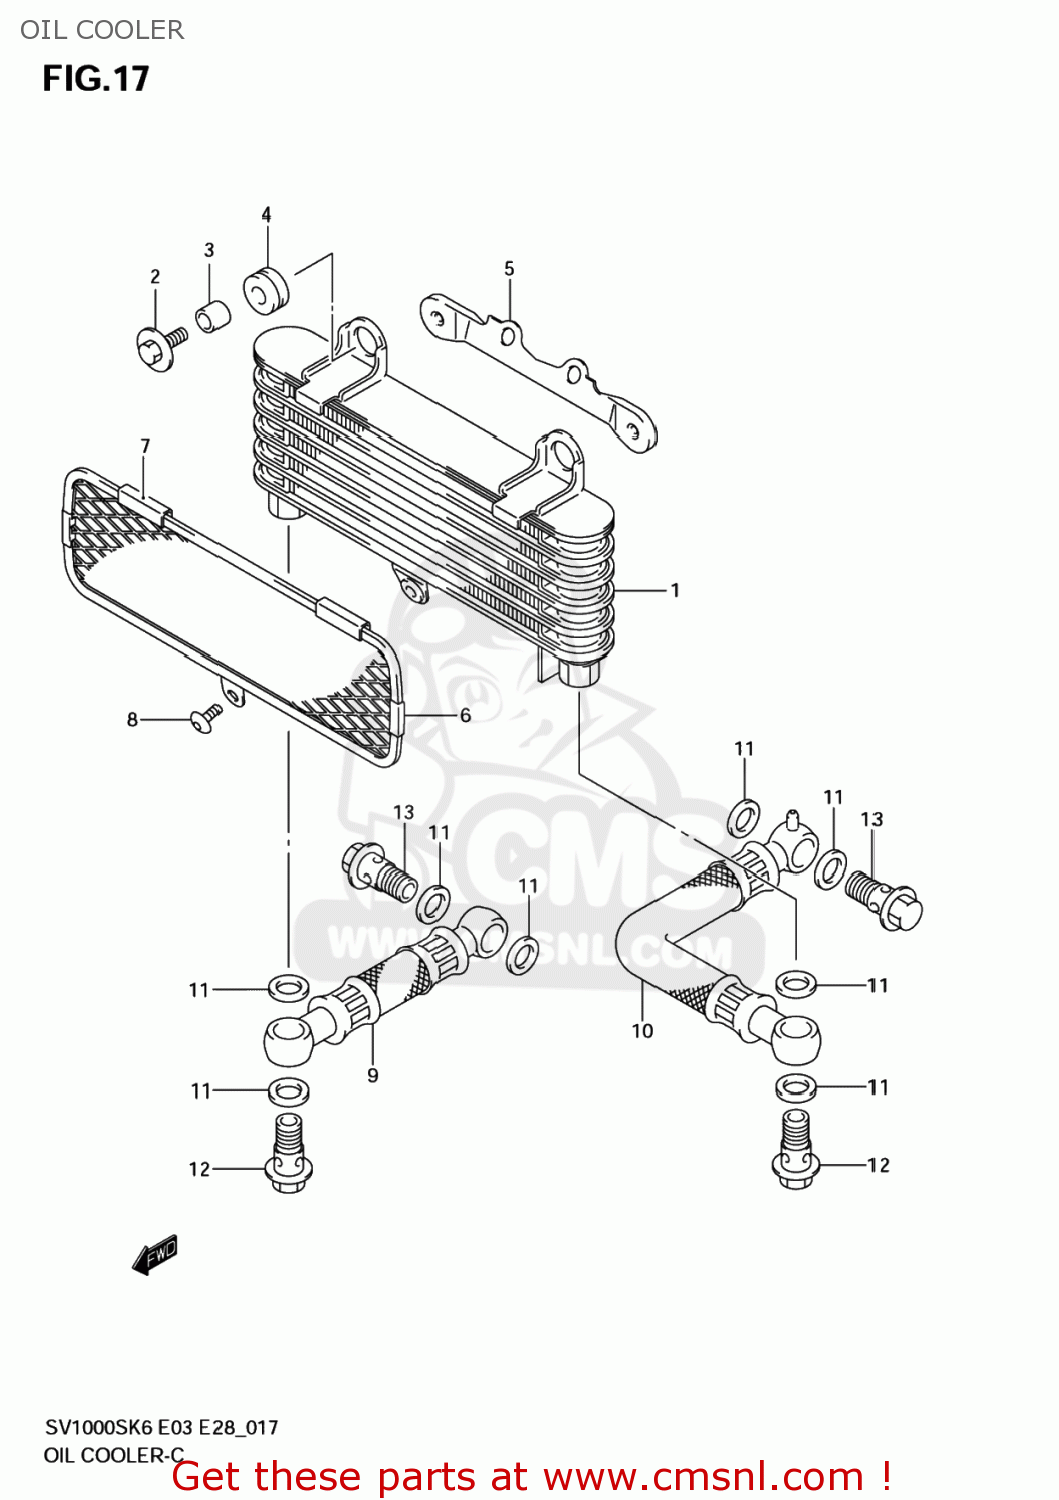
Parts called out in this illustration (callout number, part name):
1	COOLER ASSY,OIL
2	BOLT(6X20)
3	SPACER(6.5X10X10)
4	CUSHION
5	BRACKET,OIL COOLER
6	GUARD,OIL COOLER
7	PROTECTOR,CTR
8	SCREW
9	HOSE,OIL COOLER,R
10	HOSE,OIL COOLER,L
11	GASKET(14X20X1.5) (NAS)
12	BOLT UNION
13	BOLT UNION
